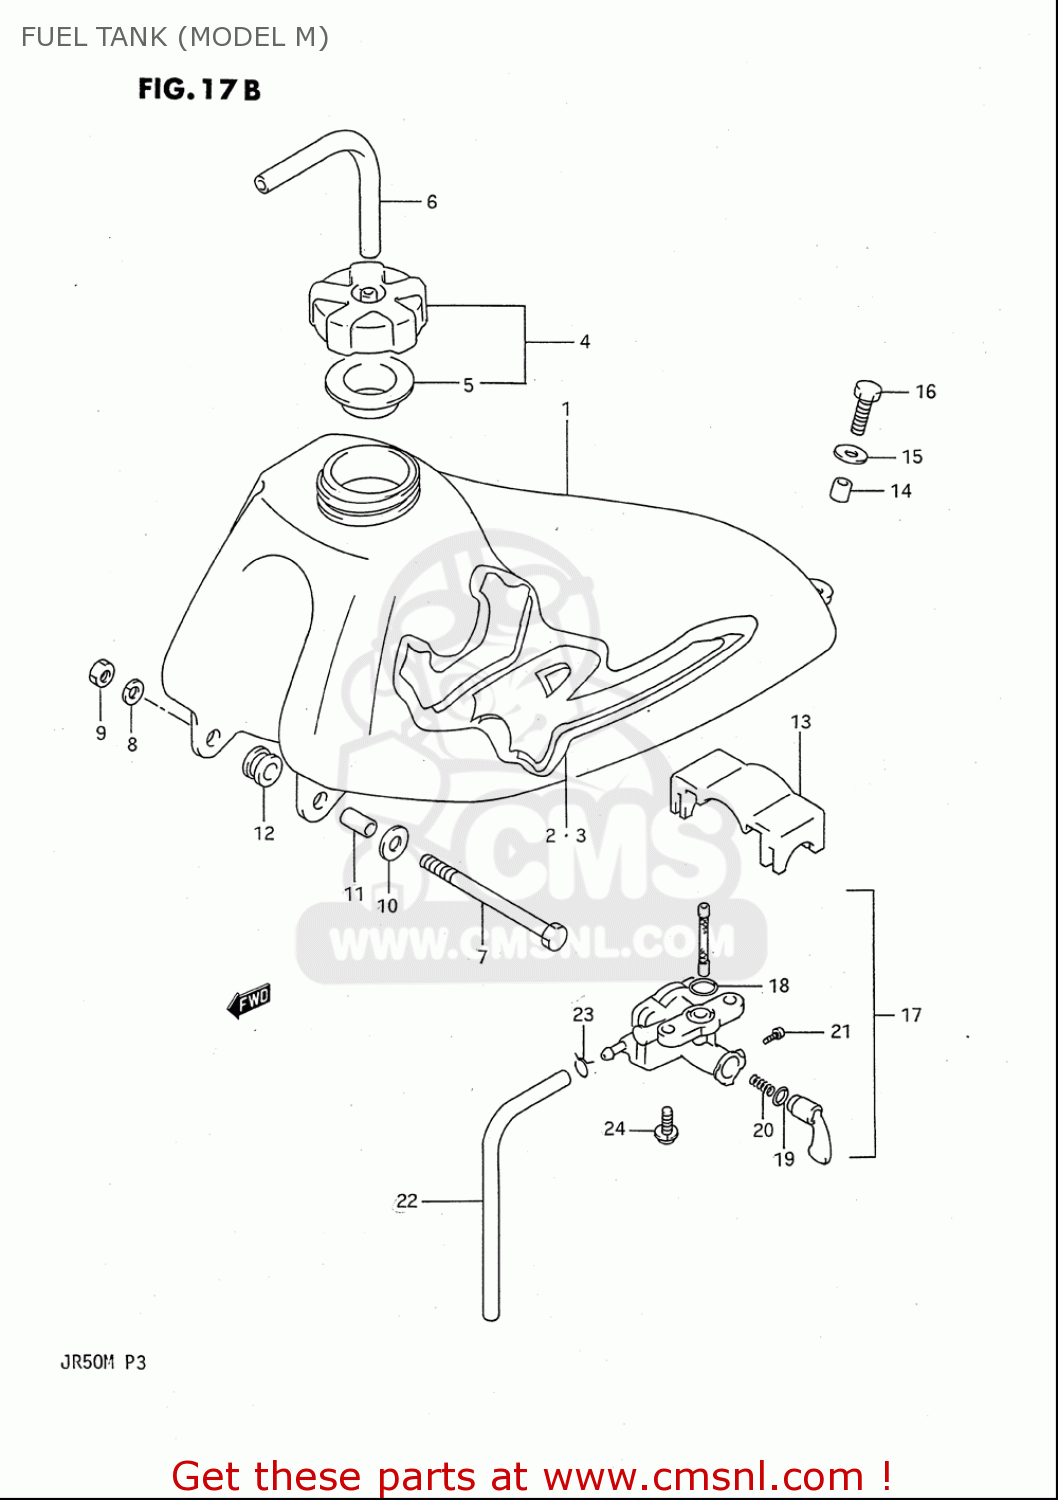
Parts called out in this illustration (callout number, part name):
1	TANK,FUEL
2	EMBLEM,FUEL TANK,RIGHT
4	CAP SET,FUEL TANK
5	GASKET (NAS)
6	HOSE(5X8.2X600)
7	BOLT
8	WASHER,LOCK
9	NUT
10	WASHER(6.5X18X1)
11	SPACER (6.8X10X11.5)
12	CUSHION
13	CUSHION,FUEL TANK UPR
14	SPACER(6.5X9X7.2)
15	WASHER(6.5X18X1)
16	BOLT
17	COCK ASSY,FUEL
18	O RING
19	O RING,LEVER
20	SPRING
21	SCREW
22	HOSE(5X8.2X600)
23	CLIP
24	SCREW
